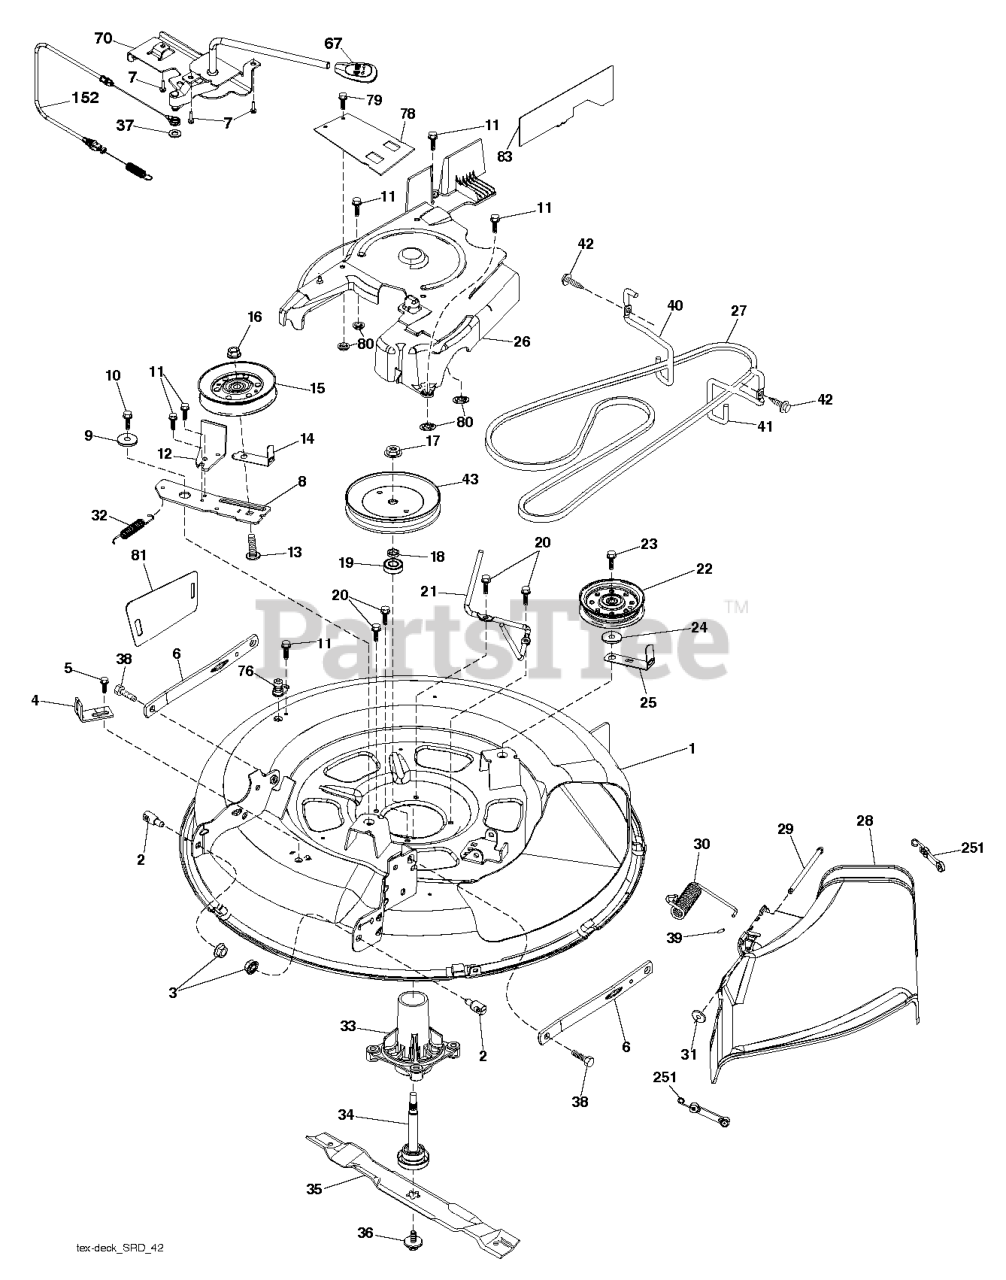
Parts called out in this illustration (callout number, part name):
1	DECK.WELDMENT.PNT.30"SRD
2	STUD.FASTNER.W/ANTI-ROTATE
3	NUT LOCK HEX FLANGE 5/16-18
4	BRACKET.CLUTCH.CABLE
5	BOLT.5/16HEX.WHS.HD
6	ARMS.SUSP.MOWER.REAR.SRD
7	SCREW.#10 X 0.750.BOS
8	ARM.IDLER.30"SRD
9	SPACER.RETAINER
10	SCREW 3/8-16X1
11	SCREW.1/4-20X5/8
12	RP ARM.BRAKE.MOWER.38"LH.TEX
13	BOLT.3/8-16X1.50
14	KEEPER, BELT IDLER
15	PULLEY.IDLER.4.25
16	NUT LOCK FLG 3/8-16 UNC
17	NUT.FLANGE.LOCK.TOP
18	WASHER.SPACER.MANDREL
20	SCREW, WASHER HEAD
21	KEEPER.BELT.MANDREL.30"
22	PULLEY.IDLER.FLAT.46.PR.DR.
23	SCREW LT
24	WASHER
25	KEEPER.BELT.30"SRD
26	COVER.ASM.MANDREL.30"
27	V-BELT.DRIVE.MOWER.30"
28	SHIELD.DEFLECT.MWR.30S.BLACK
29	PIN.HINGE.30".SRD
30	SPRING.TORSION.DEFLECT
31	NUT PUSH M
32	SPRING RETURN
33	RP.HOUSING.MANDREL.4PT.
34	SHAFT.ASM.MDRL.N/GREASE.38
35	BLADE, MULCH.LRV30
36	BOLT.WASHER.ASM.7/16-2
37	WASHER
38	BOLT.SHOULDER
39	CAP-SLEEVE LT
40	KEEPER.BELT.ENGINE.LH.LT.SRD
41	KEEPER.BELT.ENGINE.RH.LT.SRD
42	SCREW, 3/8-16X3/4
43	PULLEY, MANDREL 6.5 PD
67	HANDLE.CLUTCH.CABLE.LT
70	CLUTCH.ASM.MANUAL.LT.PRED
76	PORT.WASHOUT
78	GUARD ARM CLUTCH
79	SCREW.HI-LO.CONSOLE
80	PALNUT 1/4
81	SHIELD SUSPENSION
83	GUARD LEFT
152	CABLE.CLUTCH.MANUAL.
251	ELASTIC STRAP KIT
